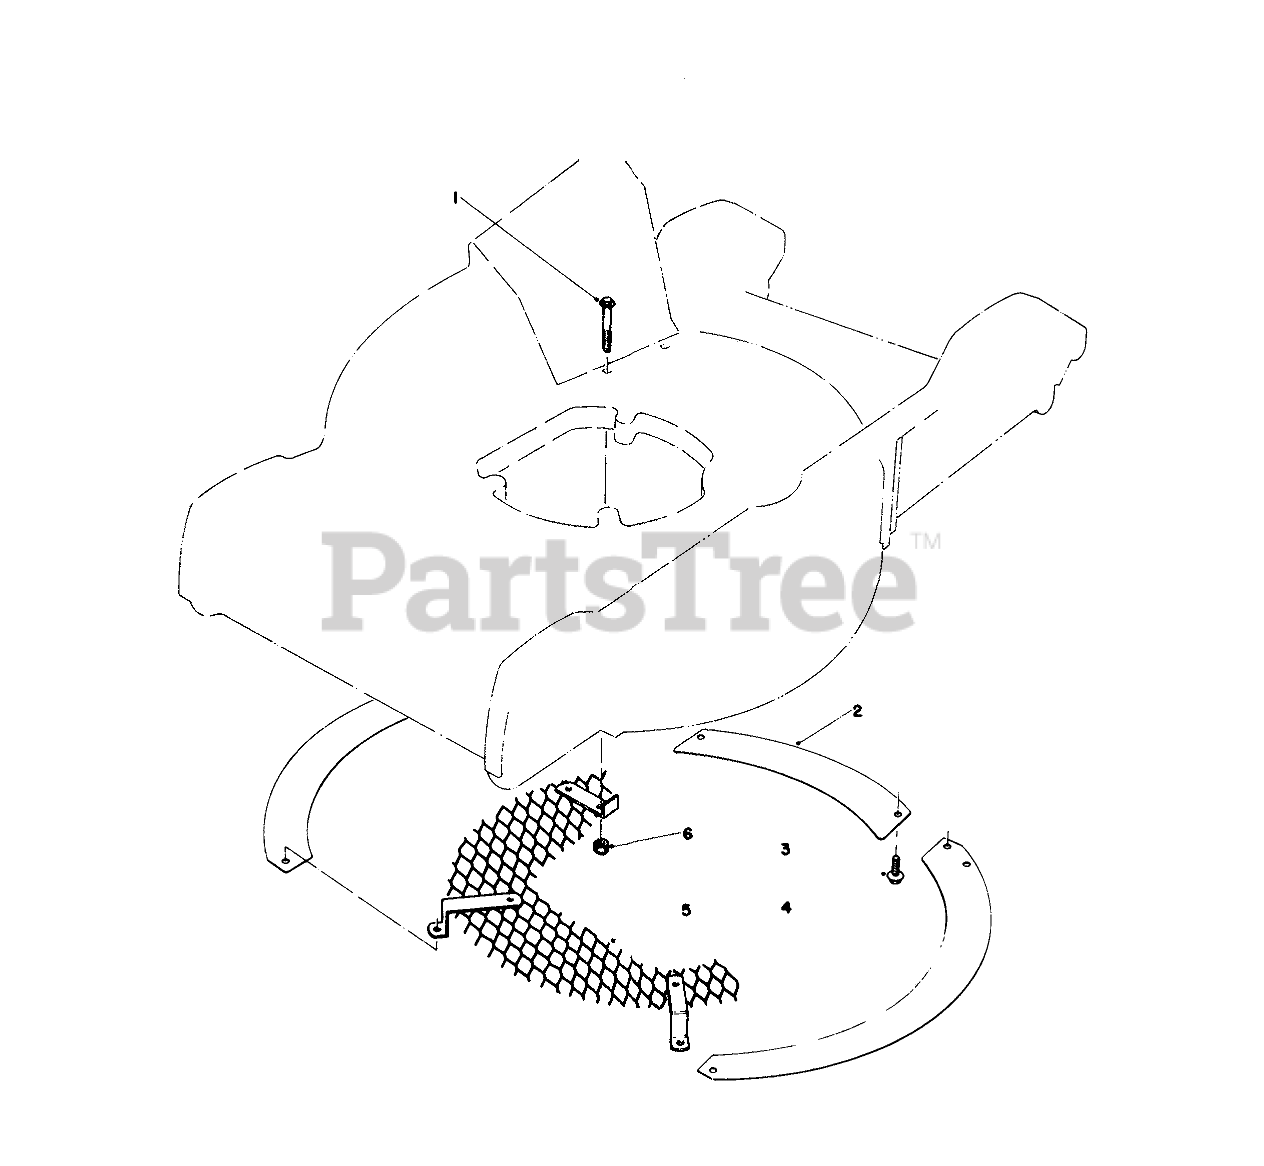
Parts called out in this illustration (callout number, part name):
1	Screw
2	Rear Baffle
3	SCREW
4	Outer Baffle
5	Screen
6	NUT-LOCK
